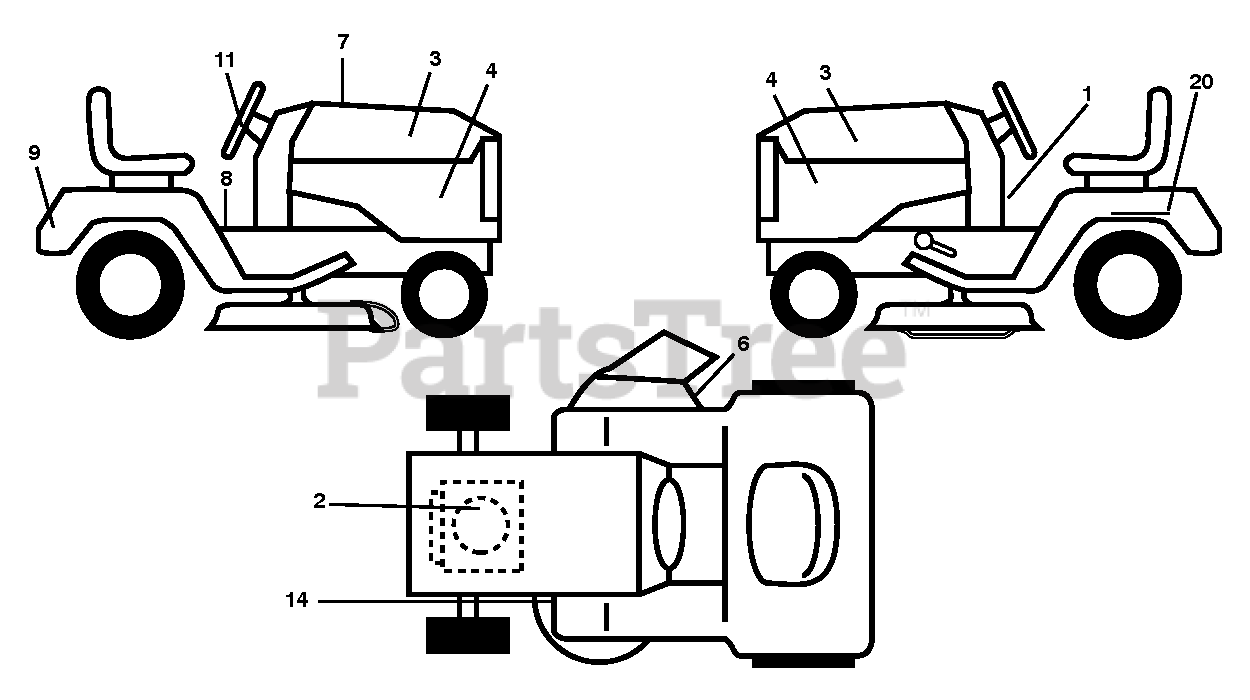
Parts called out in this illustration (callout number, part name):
1	LABEL.EPA.COMPLIANCE
2	DECAL.ENGINE.B&S.(278443)
6	DECAL.WARN.KEEP.HAND.AWAY
7	Decal Replacement Parts
8	Fender Engine Warning Decal
14	DECAL V BELT SCHEMATIC
20	DECAL BTRY SYMBOLS
